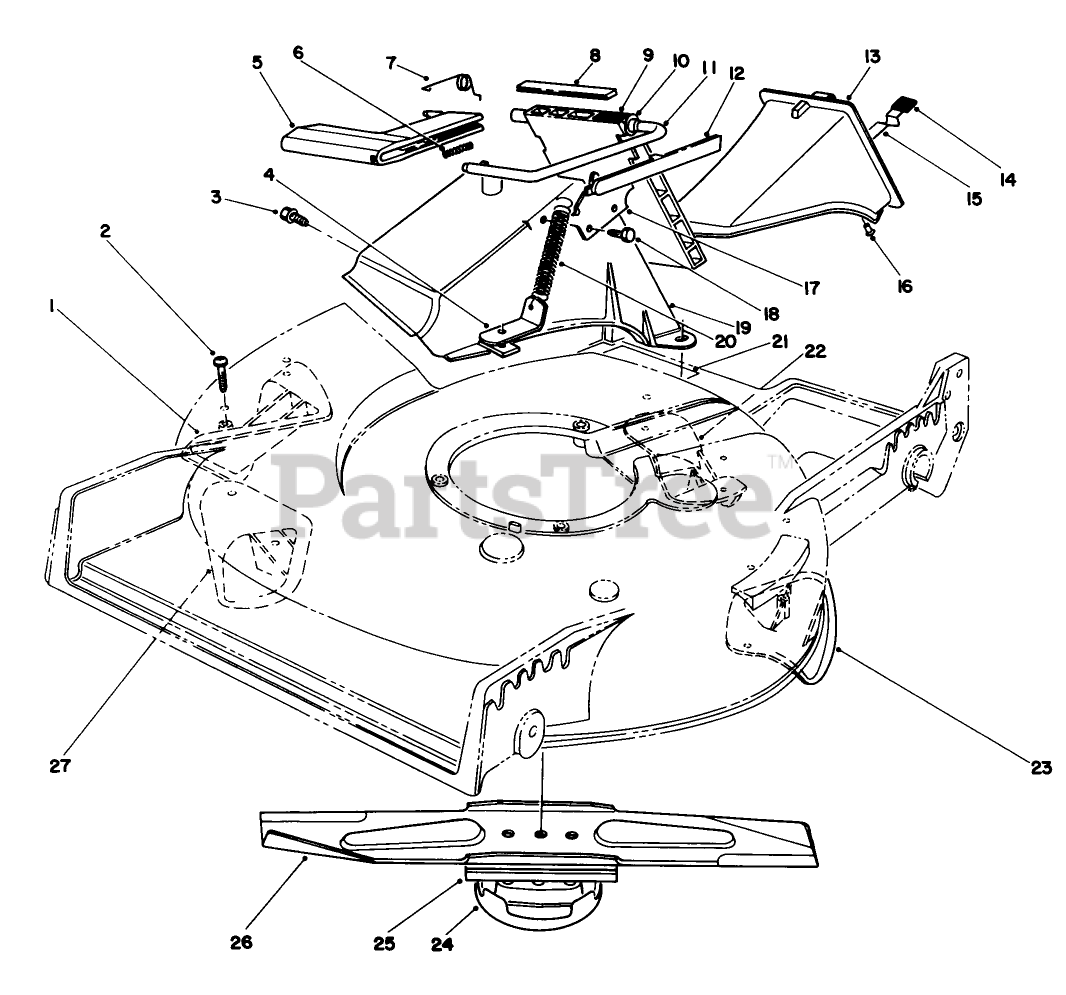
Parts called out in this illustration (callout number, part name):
1	KICKER
2	#8 X .625" PHILPS PAN H
3	SCREW AND WASHER ASM
5	ORD.77-0200 ASM
6	ORD.77-0200 ASM
7	RETAINER-DOOR
8	ORD.77-0200 ASM
10	BUSHING-NYLON
11	ORD.77-0200 ASM
12	ORD.77-0200 ASM
13	DISCHARGE PLUG ASM
14	GRIP-LATCH
15	LATCH-PLUG, DISCHARGE
16	RIVET-HEAD, FLAT
17	DOOR LATCH PLATE
18	SCREW-PLASTITE
19	DISCHARGE TUNNEL
20	SPRING-DOOR
22	KICKER
23	KICKER
24	CUP-SCALP, ANTI
27	KICKER
